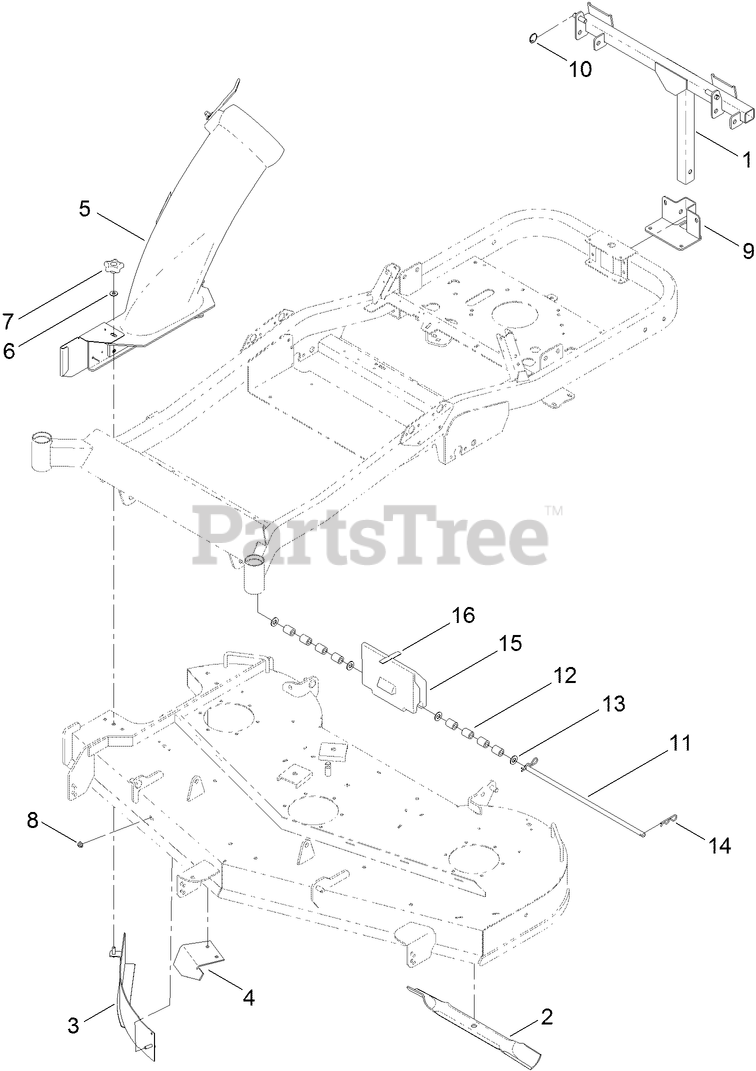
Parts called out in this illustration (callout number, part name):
1	FRAME-PIVOT
2	BLADE-20.50 INCH
3	BAFFLE-BAGGER
4	BAFFLE-CUTOFF
5	BAGGER BOOT ASM
6	WASHER-FLAT
8	NUT-HF, NI
9	SUPPORT-BAGGER
10	PIN-COTTER, CIRCULAR
11	ROD-DECK, PIVOT
12	SPACER-WHEEL
13	WASHER-FLAT
14	PIN-HAIR
15	WEIGHT-BAGGER
16	BUMPER-PAD
